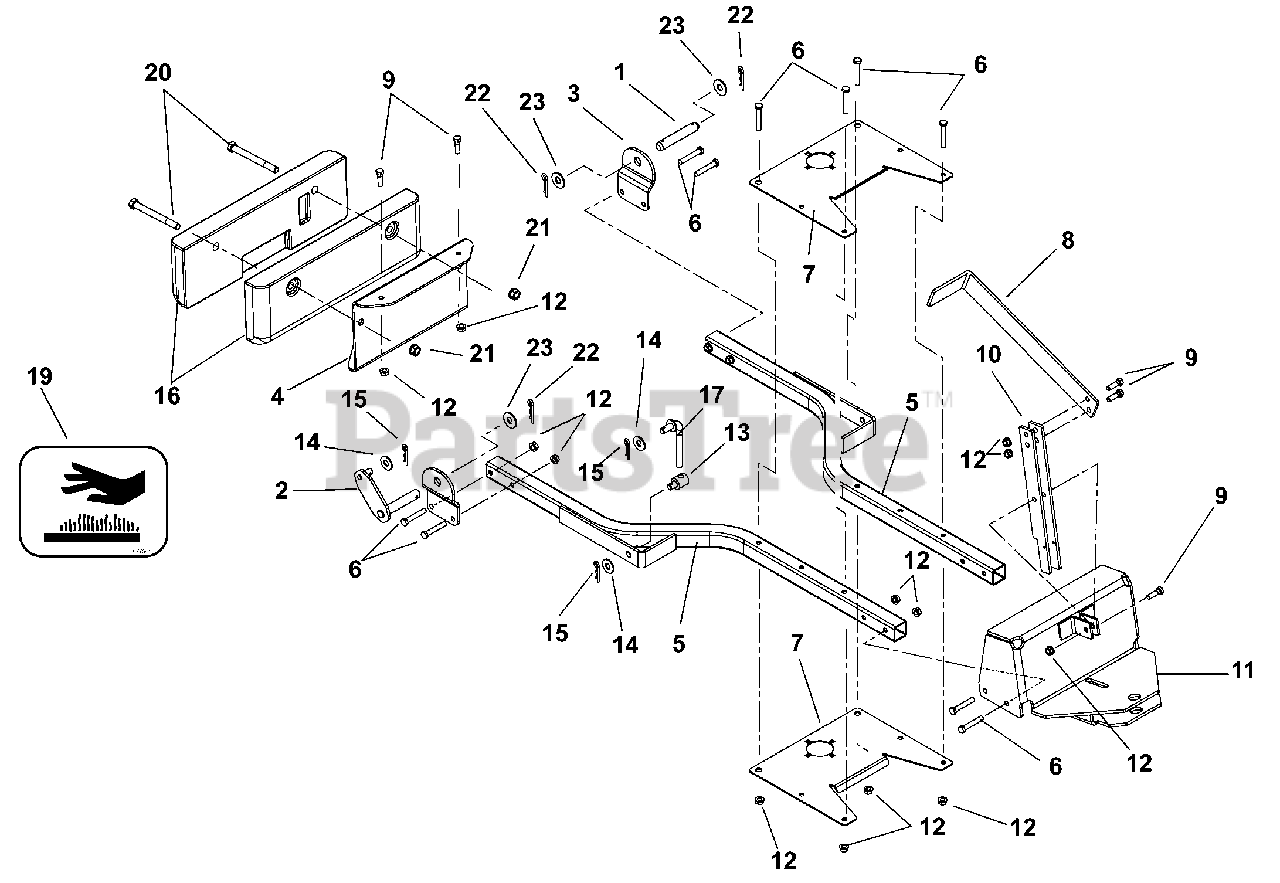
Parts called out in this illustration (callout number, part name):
1	Pin, Left Rear Lift Pivot
2	Bracket, Right Rear Lift Pivot
3	Bracket, Pivot
4	Weight Bracket
5	Sub-Frame Tube
6	Hex Bolt, .38-16 x 2.25 Gr 5
7	Sub-Frame Plate
9	Hex Bolt, .38-16 x 1.25 Gr 5
11	Blade Mount Yoke
12	Top Locking Flange Nut, .38-16
13	Trunnion
14	Flat Steel Washer, .531 x 1.250 x .100
15	External Hair Pin, #16
16	Weight, Cast Iron
17	Lift Link
18	Tire/Wheel Assembly, 18 x 16.5
19	Decal, Hot Surface
20	Bolt, Hex .50-13 x 5.00 Gr 5
21	Nut, Top Locking Flange, .50-13
22	Pin, Hair .15 x 2.937
23	Washer, Flat Steel .812 x 1.50 x .135
